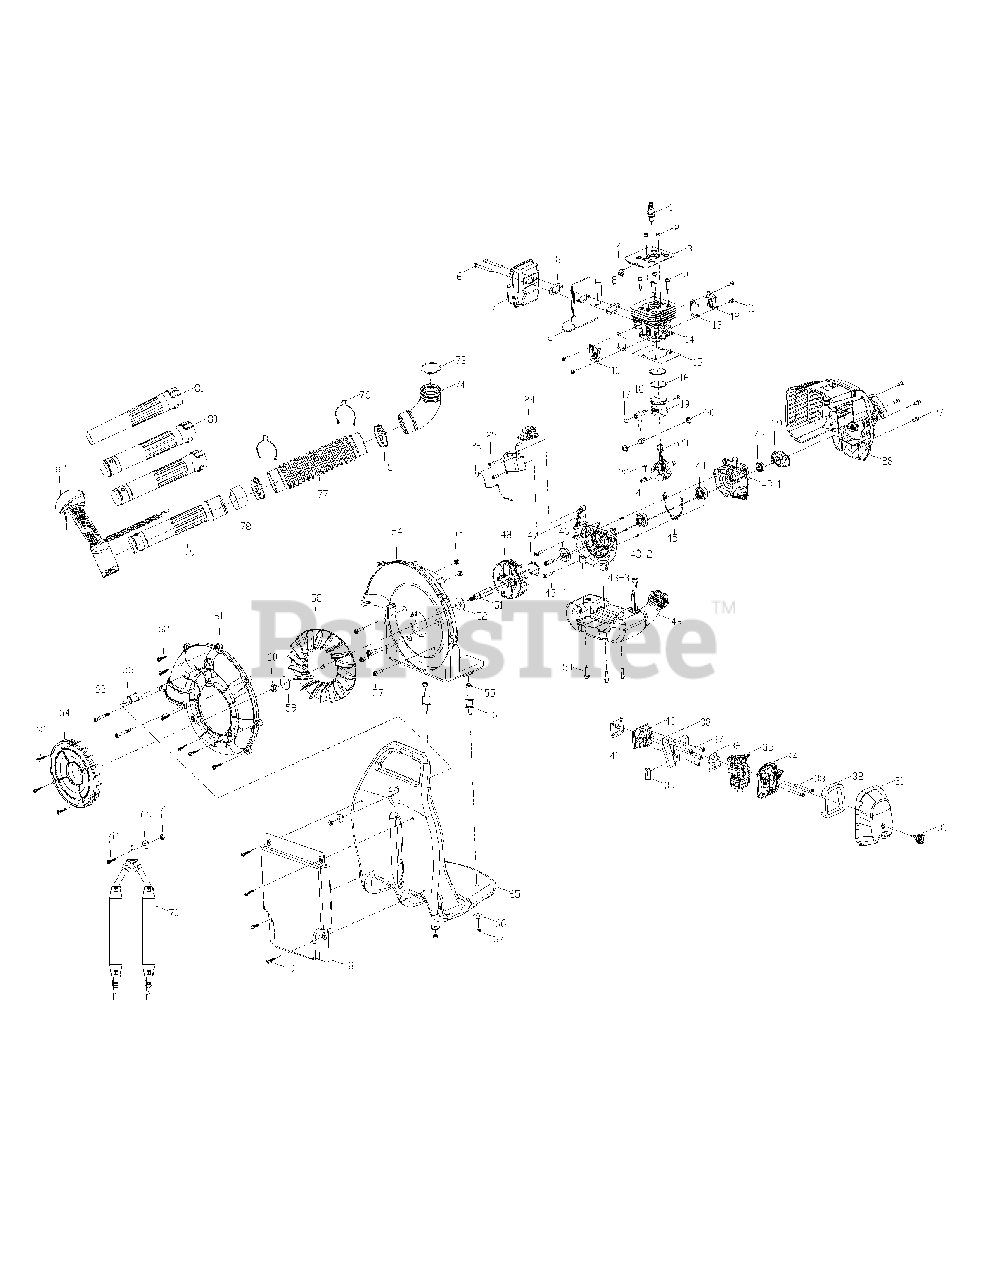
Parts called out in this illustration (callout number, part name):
1	SPARK PLUG
3	PLATE, SPARK SIDE
7	MUFFLER ASS'Y
8	MUFFLER GASKET
9	MUFFLER PLATE
10	COVER, FLYWHEEL SIDE
12	COVER, STARTER SIDE
14	CYLINDER
16	PISTON RING
18	PISTON PIN
20	AXIS COVER
21	NEEDLE BEARING
23	CRANK/ROD ASS'Y
24	IGNITION COIL
26	COIL WIRE
28	STARTER HOUSING ASS'Y
29	PAWLS ASS'Y
30	SCREW
31	FILTER COVER
34	FILTER ASS'Y
35	CARBURETOR
36	CARBURETOR GASKET
40	INSULATOR
41	INSULATOR GASKET
43	CRANKCASE ASS'Y
43-1	CRANKCASE, STARTWE SIDE
43-3	CRANKCASE, FLYWHEEL SIDE
45	GASKET, CRANKCASE SIDE
47	C RING
49	FUEL TANK ASS'Y
51	CONNECT AXIS
52	WASHER
53	NUT
54	SCREW HOUSING
55	NUT
56	VIBRO-ISOLATING RUBBER
59	WASHER
60	NUT
61	SCREW HOUSING
62	SCREW
68	CUSHION BACK
69	RIVET RIBBED
74	ELBOW PIPE
75	HOSE BEND
76	WIRE CLAMP
77	FLEX PIPE
78	ACTIVE RING
79	BASE PIPE
80	MIDDLE PIPE
82	THROTTLE LEVER ASS'Y
